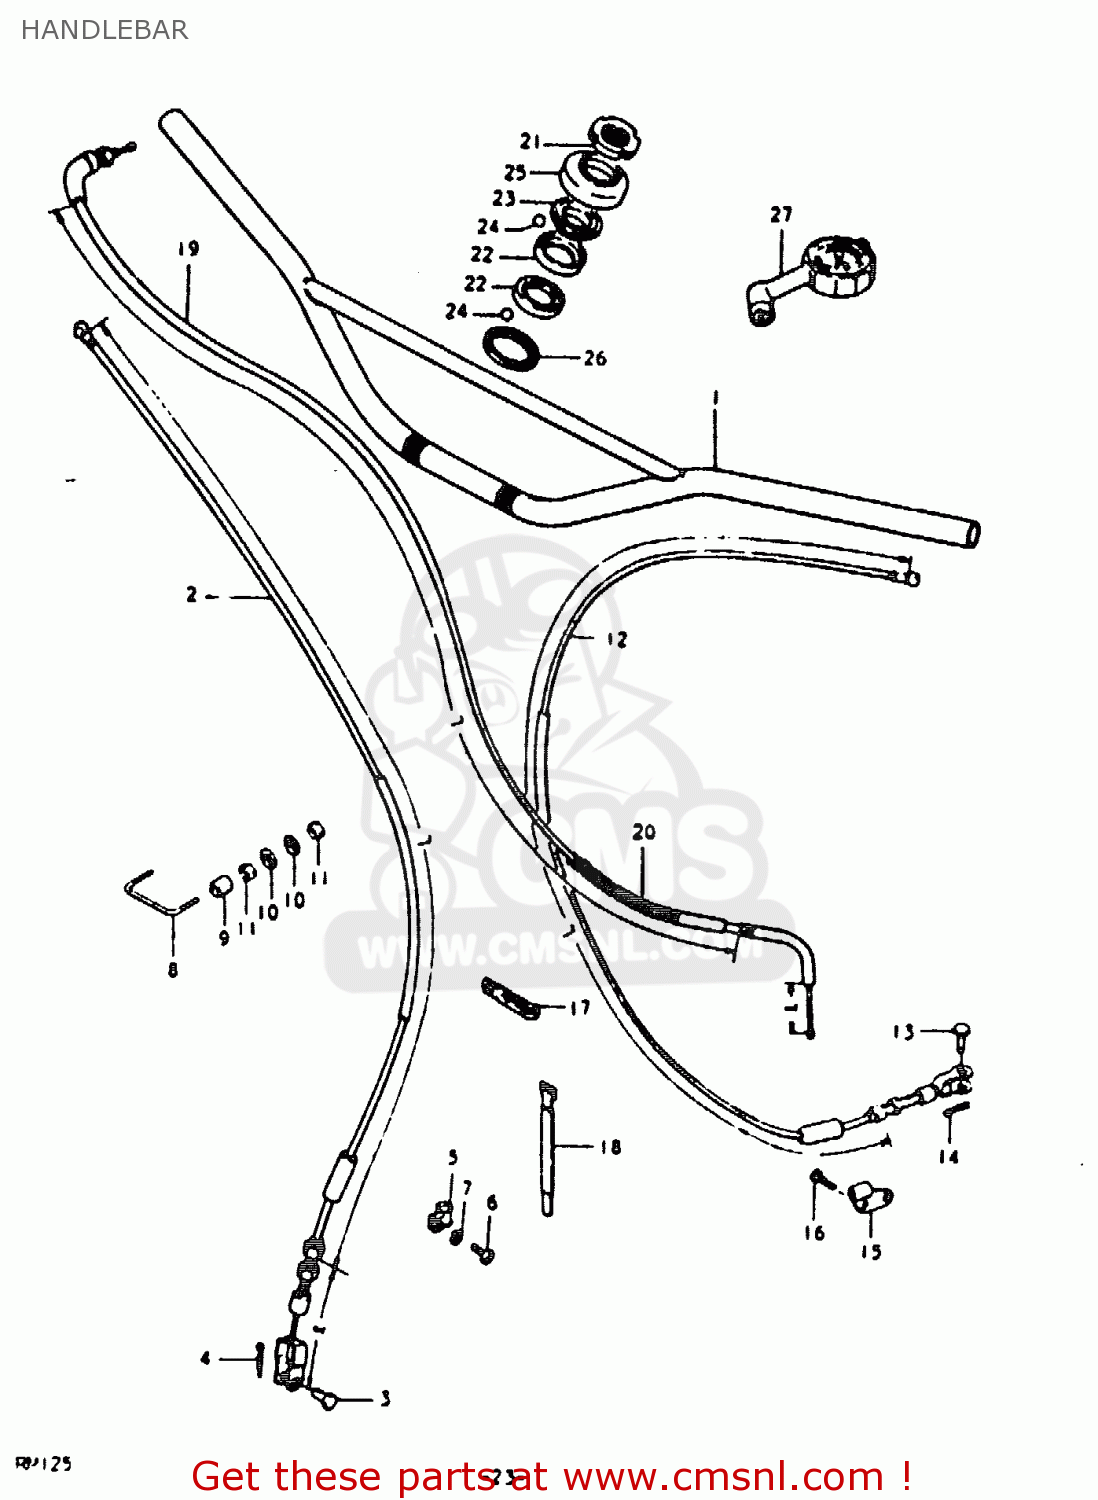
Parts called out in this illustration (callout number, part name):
1	HANDLEBAR
2	CABLE ASSEMBLY,FRONT BRAKE
3	PIN(L:17.5)
4	PIN
8	CLAMP,CABLE
9	BUSHING
10	WASHER
11	NUT 3MM
12	CABLE ASSY,CLUTCH
13	PIN(L:13)
14	PIN
15	STOPPER,CLUTCH CABLE
16	SCREW
17	CLAMP L:35
18	CLAMP
19	CABLE ASSEMBLY,THROTTLE
20	PROTECTOR,CABLE
21	NUT,STEERING STEM
22	RACE,STEERING,INNER,UPPER
23	RACE,STEERING,OUTER,UPPER
24	BALL
25	SEAL,STEERING UPR DUST
26	DUST SEAL,STEERING HEAD
27	GAUGE ASSY,AIR PRESSURE
